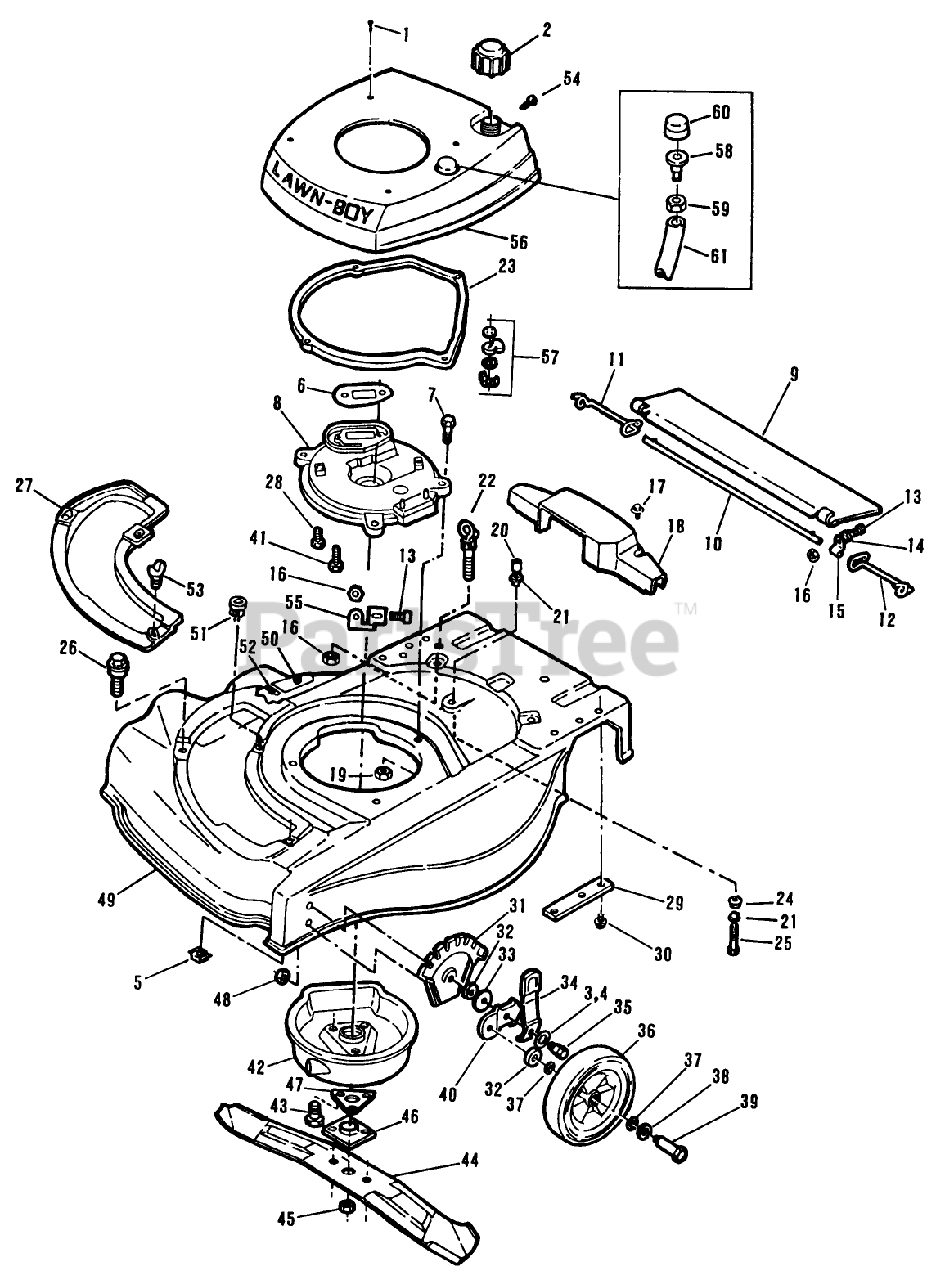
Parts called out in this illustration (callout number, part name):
1	SCREW LAWRENCE
2	FUEL CAP & INSERT
3	WASHER
4	WASHER
5	NUT-CAGE
6	GASKET-EXHAUST F
7	SCREW-HH
8	PLATE,MUFFLER F
10	ROD T/SHIELD ADV WIRE
11	SPRING;TRAILING SHIELD RH
12	SPRIG T/SHLD ASOC
14	Washer-Trailing Shield
15	CLAMP ROD KMC
16	LOCKNUT E
17	SCREW SEMS TRM HEX HD
19	NUT-LOCK F
20	SPACER
21	SPACER ECK PRES
22	BOLT-EYE
30	SCREW
31	PLATE HGT ADJ TRO
32	WASHER WROUGHT
33	WASHER
34	KNOB&SPRING FORMCO
35	BOLT
36	WHEEL & TIRE KIT
37	WASHER
38	SPACER
39	BOLT WHEEL
41	SCREW V
43	SCREW
45	NUT-BLADE
46	PLATE AND COLLAR ASM
47	SUPPORT F
48	LOCKNUT
53	WING SCREW LAWRE
54	SCREW S
56	SHROUD,TANK&VAVLE
59	LOCKNUT S
60	P-BULB LAV-RUB
61	TUBING-PRIMER POLY
